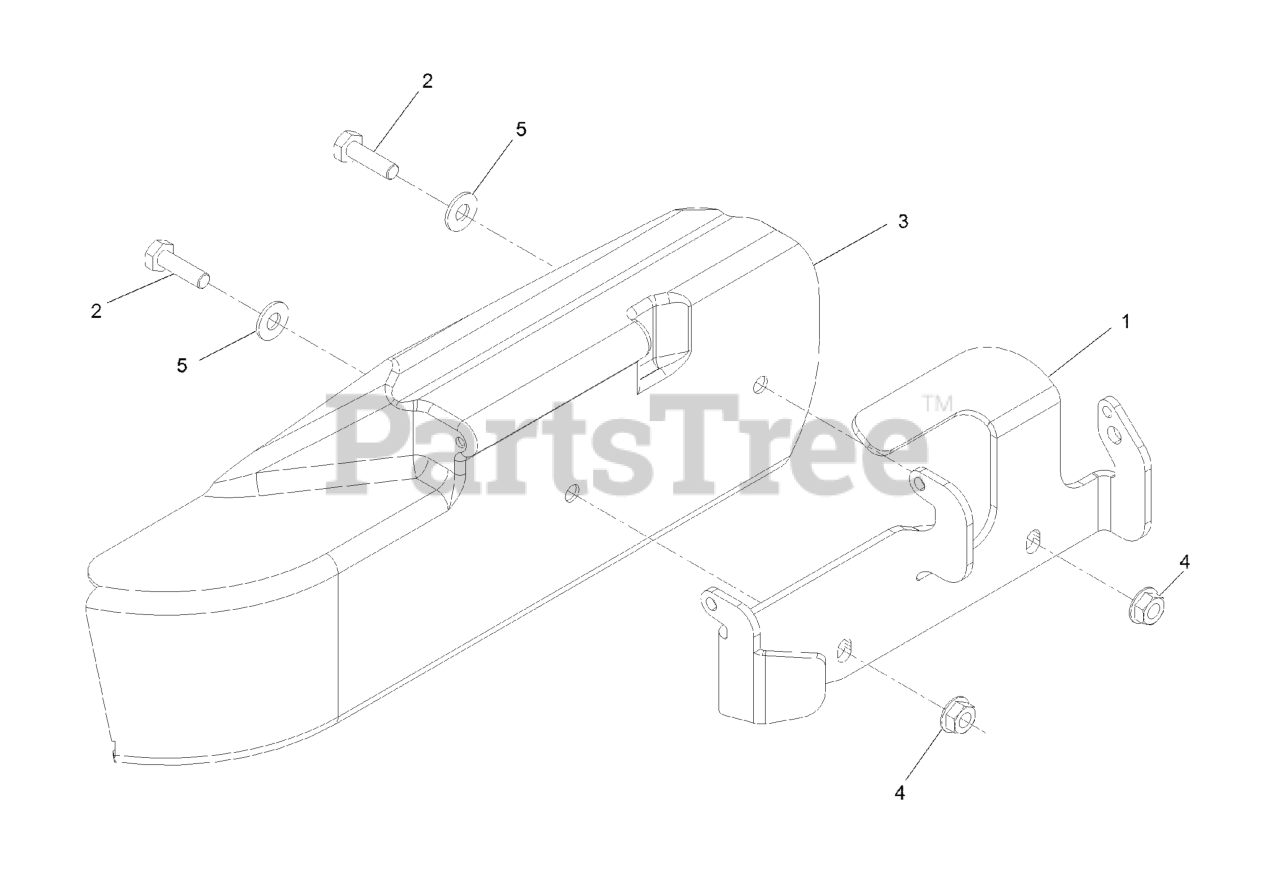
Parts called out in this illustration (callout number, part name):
1	BRACKET-DEFLECTOR, SIDE
2	SCREW-HH
3	DEFLECTOR-SIDE
5	WASHER-FLAT
